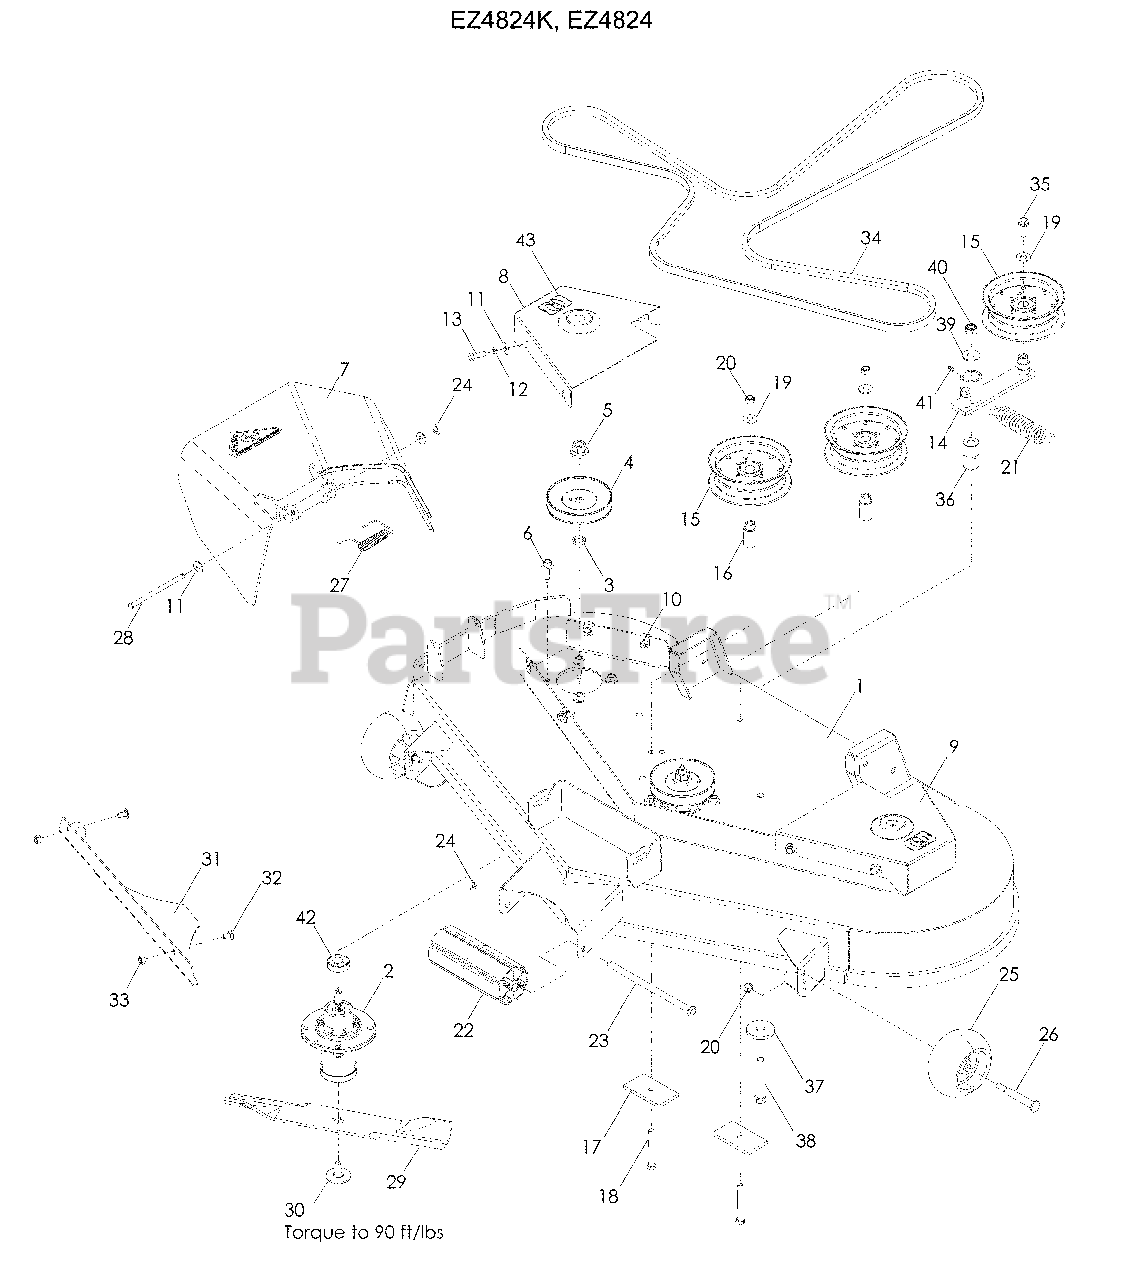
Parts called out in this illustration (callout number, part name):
1	DECK, w/DECALS
2	HOUSING ASSM
3	WASHER, SPACER
4	PULLEY, MANDREL
5	NUT 9/16 TOP CNTRLK
6	SCREW 5/16 -18 x WSH HD
7	CHUTE, DISCHARGE
8	BELT SHIELD, RT
9	BELT SHIELD, LT
10	RETAINER, U TYPE
11	WASHER 5/16 STD FLAT
12	WASHER 5/16 SLW
13	HCS 5/16-18 x ¾
14	ARM, IDLER
15	PULLEY, IDLER
16	BUSHING, IDLER
17	PAD, PAINTED
18	HCS 3/8-16 x 3
19	WASHER 3/8 FLAT STD
20	NUT 3/8-16 HEX NYLOC
22	ROLLER, NOSE
23	ROD, ROLLER, NOSE
24	PIN, COTTER 1/8 x ¾
25	WHEEL, GAUGE
26	BOLT ½-16 x 25/8 SHOULDER
27	SPRING, TORSION
28	PIN, CLEVIS 5/16
30	BOLT 7/16 BLADE
31	PLATE, CONFINEMENT
32	RHSNB 5/16-18 x 5/8
33	NUT 5/16-18 HEX NYLOC
34	BELT, DECK
35	HCS 3/8-16 x 1 WHIZLK
36	BUSHING, PIVOT
37	WASHER, SUPPORT
38	HCS ½-13 x 3¼
39	WASHER ½ STD FLAT
40	NUT ½ HEX NYLOC
41	ZERK
42	BEARING, BALL
43	DECAL, NO STEP
